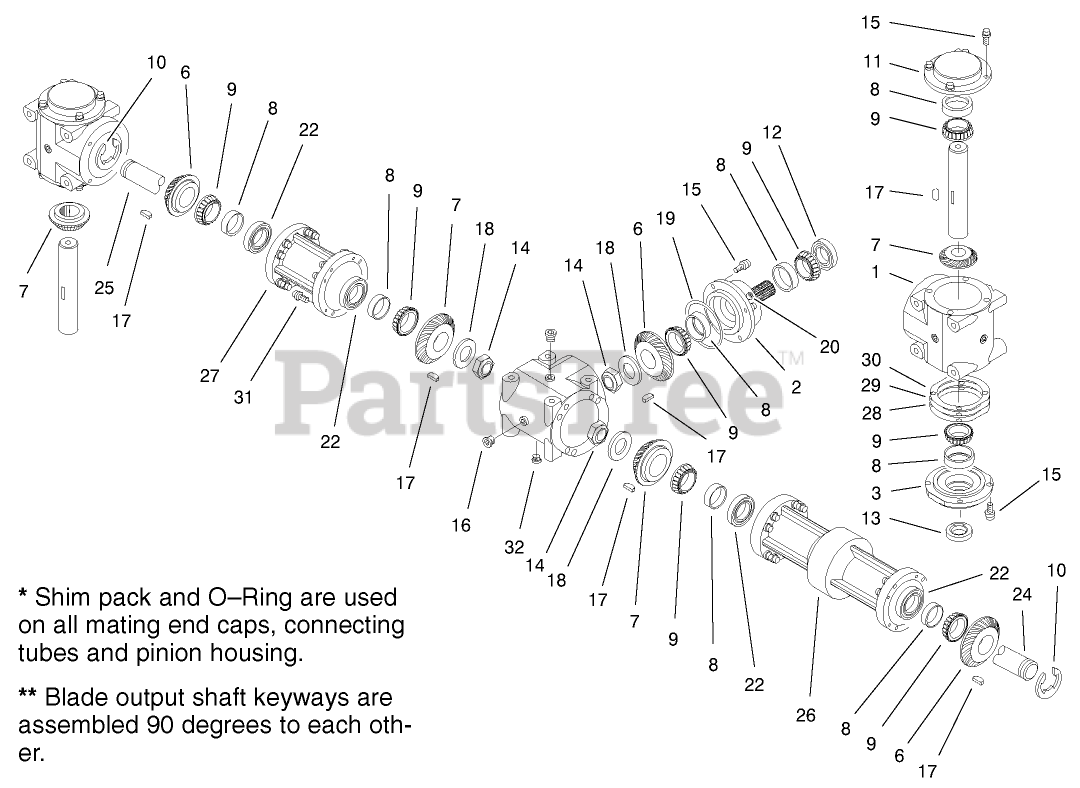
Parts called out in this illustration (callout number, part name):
2	HOUSING - PINION
3	CAP-END, OPEN
6	GEAR - 27 TOOTH
7	GEAR - 29 TOOTH
8	Bearing-Cup
9	Bearing-Cone
10	CLIP-RETAINING
11	CAP-END, CLOSED
13	SEAL
14	NUT-JAM
17	KEY-WOODRUFF
18	WASHER
19	O-RING
24	SHAFT - CONNECTING, LONG
25	SHAFT - CONNECTING, SHORT
26	FLANGE - CONNECTING, LONG
27	FLANGE - CONNECTING, SHORT
28	SHIM-BROWN, .010IN
29	SHIM-BLUE, .005IN
30	SHIM-GREEN, .003IN
32	PLUG-MAGNETIC
